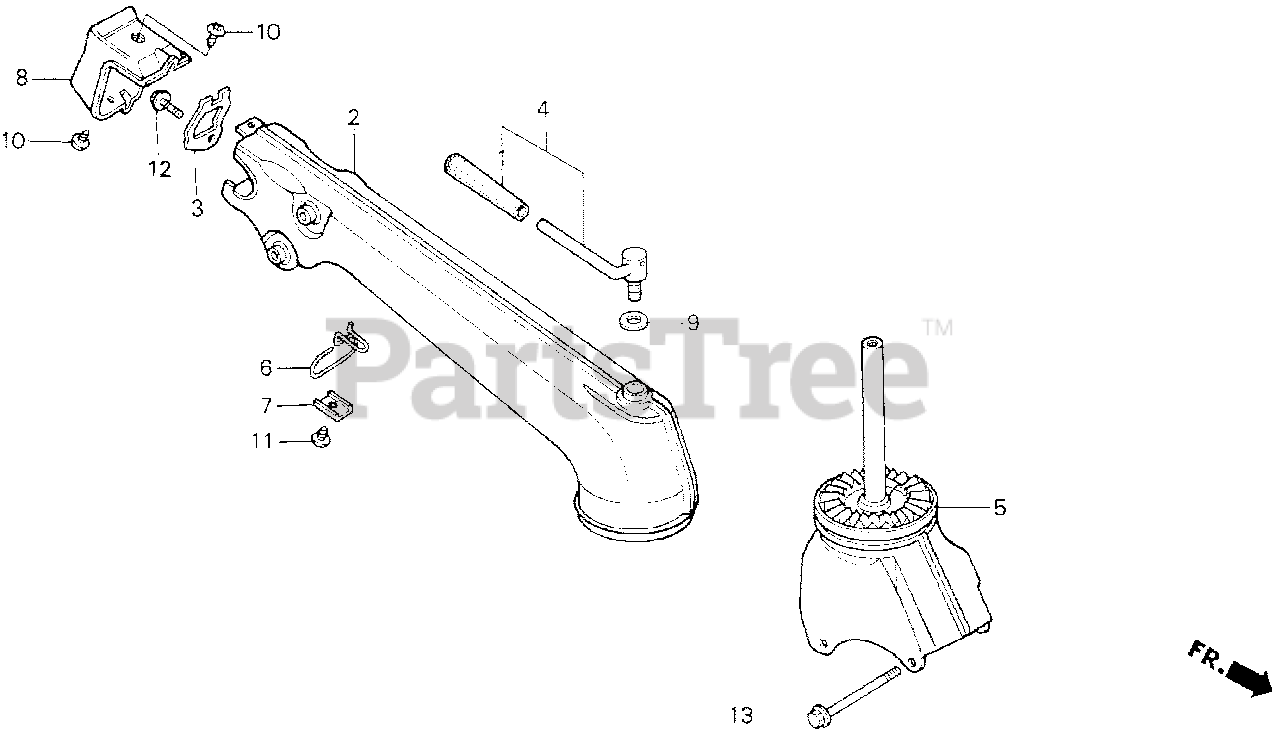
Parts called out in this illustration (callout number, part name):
1	GRIP, LEVER
2	COLUMN, HANDLE *R8* (BRIGHT RED)
3	PLATE, HANDLE LOCK
4	LEVER, HANDLE ADJUSTING
5	BASE, SWING
6	GUIDE, CABLE
7	BRACKET, CABLE GUIDE
8	DASHBOARD, COLUMN *NH31* (MCKINLEY WHITE)
9	WASHER (10MM)
10	SCREW, TAPPING (5X8) (NOT AVAILABLE)
11	SCREW, TAPPING (5X8) (NOT AVAILABLE)
12	BOLT, FLANGE (6X12)
13	BOLT, FLANGE (10X95)
